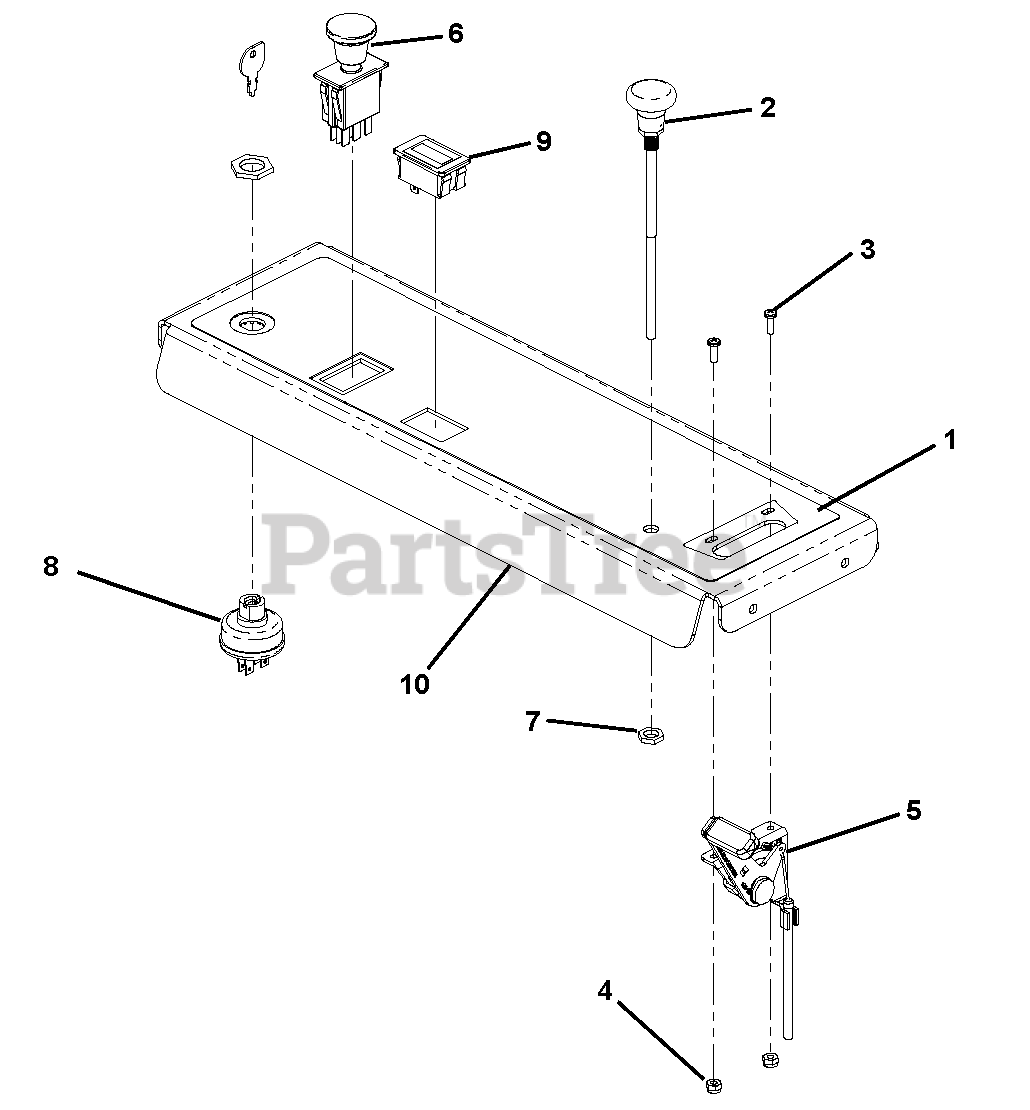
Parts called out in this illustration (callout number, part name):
1	DECAL, CONSOLE GRAVELY PROSTAN
2	CABLE,CHOKE
3	SCR-PANHDPHLPS 8-32X.50 YWZC
4	@NUT-LK-NYL 8-32 W/INSTR YWZC
5	CABLE,THROTTLE
6	SWITCH, CLUTCH (WITH GRAPHIC)
7	@NUT-HEX .38-16 YWZC
8	SWITCH, KEY - 3 POSITION
9	METER, HOUR W/MAINTENANCE
10	CONTOL PANEL ARIENS W/DECALS
